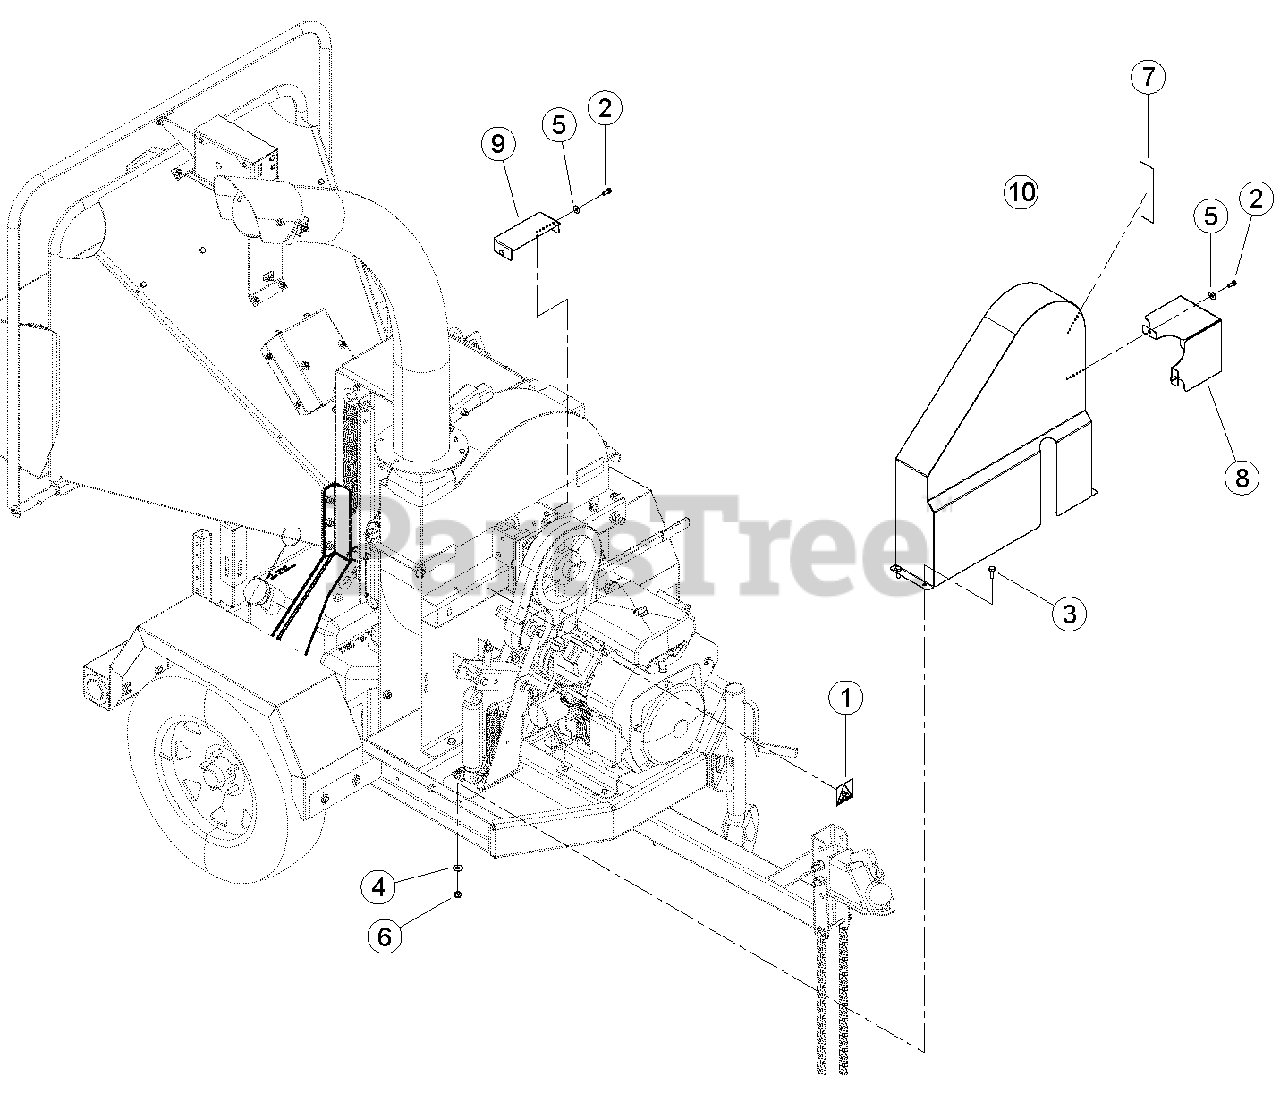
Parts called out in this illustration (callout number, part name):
1	DECAL, SHIELD DANGER ISO
2	BOLT, 5/16 X 3/4 HEX HD
3	BOLT, 3/8 NC X 1 HEX HD GR5 ZP
4	WASHER, 3/8 FLAT ZP
5	WASHER, 5/16 FLAT ZP
6	NUT, 3/8 NYLOCK
7	DECAL, CHIPPER ENGAGEMENT
8	COVER, CHIPPER VALVE
9	COVER, CHIPPER SHAFT
10	WELDMENT, BELT SHIELD
